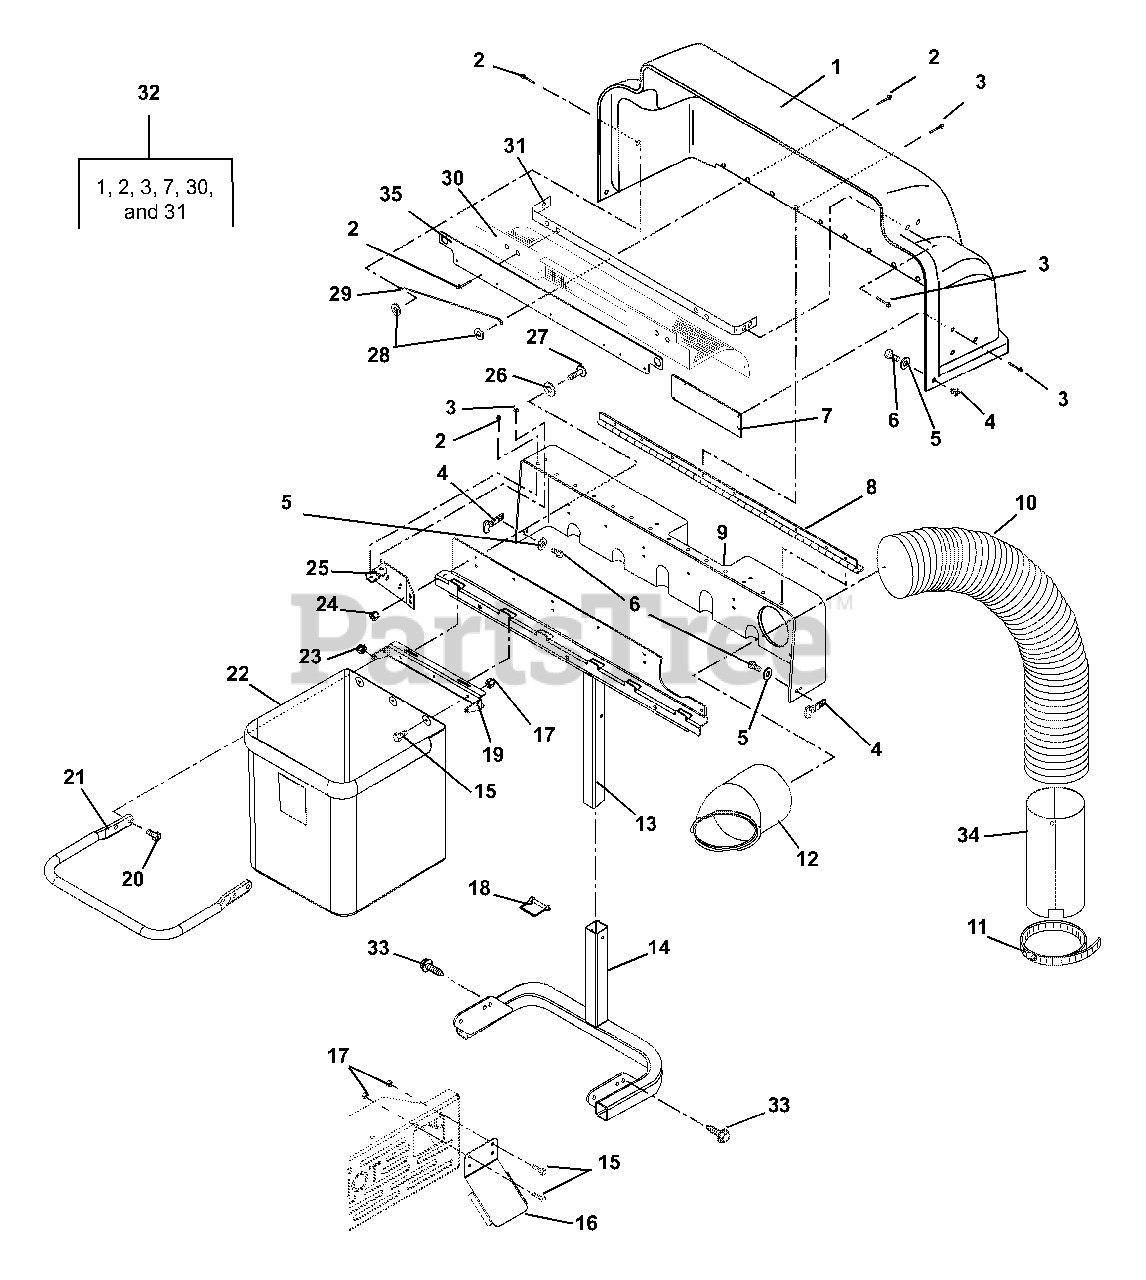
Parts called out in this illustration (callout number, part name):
1	Hinged Cover with Decal
2	Rivet-Pop .187 x .527
2	(Gravely Part Number)
3	Rivet-Pop .187 x .402
4	Latch, Rubber
5	Washer-Flat-Steel .219 x .50 x .049
6	Screw-Machine 10-24 x .50 Hex Washer Head
9	Stationary Cover
9	(Gravely Part Number)
10	Hose 7 x 45
11	Clamp-Hose Worm 2.13/8.62 x .56
11	(Gravely Part Number)
12	Bagger Boot- Upper
12	(Gravely Part Number)
13	Weldment-Bagger Frame
14	Weldment-Bumper
15	Bolt-Hex .25-20 x .50 Grade 5
16	Deflector, Exhaust
17	Nut-Locking-Center .25-20
18	Pin-.38 x 2.50 Square Lock
19	Weldment, Hanger Frame
20	Bolt-Round Head Square Short Neck .31-18 x .75 Grade 5
21	Frame-Bag Support
22	Bag-Mesh Assist Bagger
23	Nut-Spin Lock-Flange .312-18
24	Nut- Locking-Nylon .312-18 Grade 2
25	(Gravely Part Number)
26	Washer-Flat-Steel .38 x .875 x .083
27	Bolt-Hex .31-18 x .75 Grade 5
28	Washer-Flat-Steel .219 x .50 x .049
29	(Gravely Part Number)
31	Screen Mounting Bracket
32	Hinged Cover Assembly
33	Screw-Tapping .38-16 x .75 Hex Washer Head
34	Adapter, Bagger Hose
35	Guard, Screen
